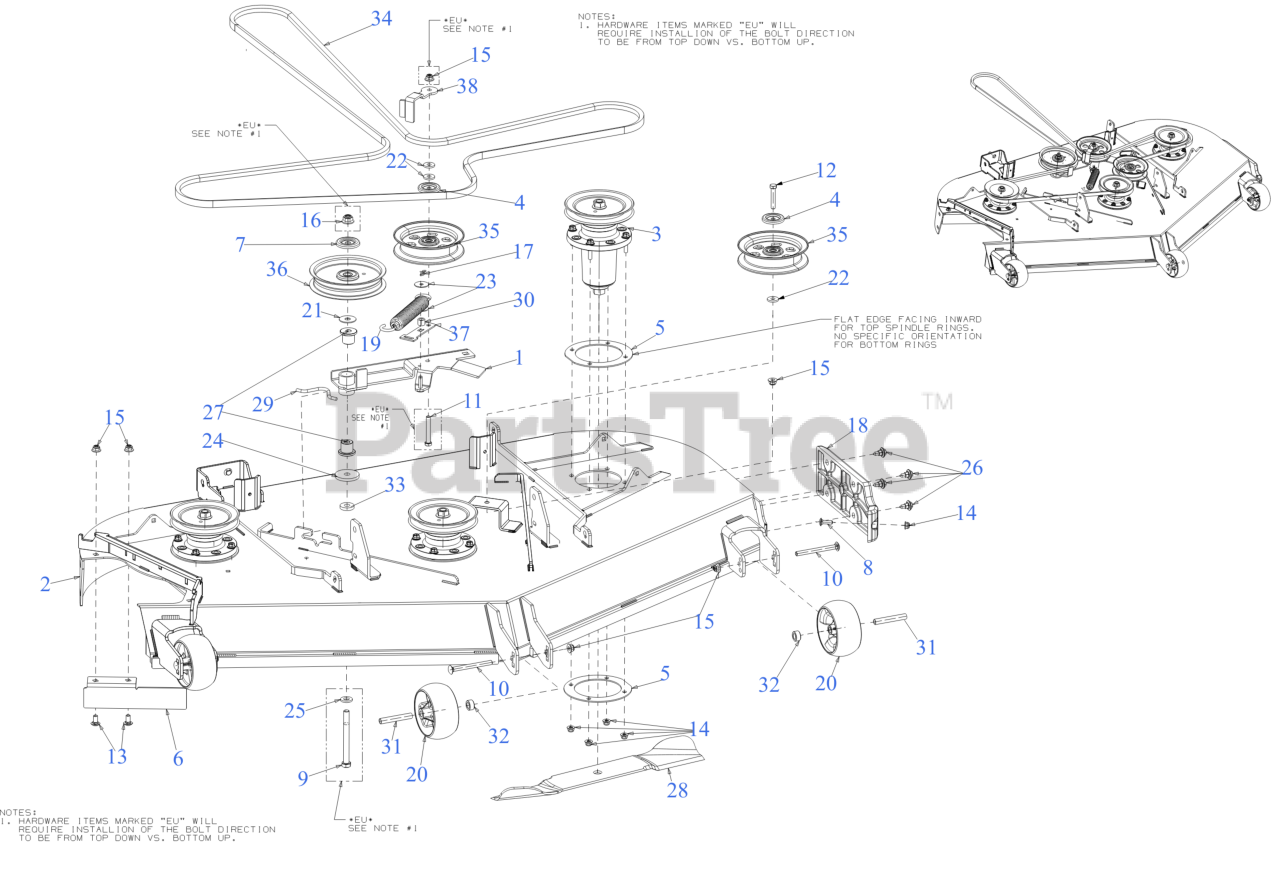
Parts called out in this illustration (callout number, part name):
1	54/60" DECK IDLER ASSEMBLY
2	60" FAB DECK SHELL
3	SPINDLE ASSEMBLY
3	Cub Cadet 60" SPINDLE ASSEMBLY (07386)
4	PULLEY CAP 1.875 DIA
5	SPINDLE PLATE
6	60" DECK CHUTE BAFFLE
7	PULLEY CAP (.540 x 2.041 DIA)
8	CARRIAGE BOLT 5/16-18 x 1.00
9	BOLT-HEX 1/2-13X5.0 GR5
10	CARRIAGE BOLT 3/8-16 x 4.00 GR5
11	HEX SCREW-3/8-16X2.5 GR5
12	SCREW 3/8-16 x 2.0 GR5
13	CARRIAGE BOLT 3/8-16 x .75
14	FLANGE LOCK NUT 5/16-18
17	BOW TIE COTTER PIN 1/4-5/16
18	DECK SKID PLATE
19	SPRING 1.25" DIA x 8.5" LONG
20	DECK WHEEL
20	WHEELS-DELUXE 5"
21	WASHER .51 x 1.5 x .07
22	FLAT WASHER .385 x 1.00 x .135
23	FLAT WASHER .322 ID x 1.25 x .060
24	FLAT WASHER .53"x2.125"x.25"
25	FLAT WASHER .531X1.060X.134
26	SHOULDER SCREW .43X.29X5/16-18 TT
27	FLANGE BEARING
29	DECK SPRING HOOK
31	SPACER .38X.49X3.05LG
32	SPACER-.505 1D
33	SPACER PLATE
34	V-BELT B SEC x 162.25
34	Cub Cadet DECK BELT
35	5" FLAT IDLER PULLEY
36	IDLER PULLEY 6.0"
37	BELT KEEPER
38	54/60" IDLER KEEPER
